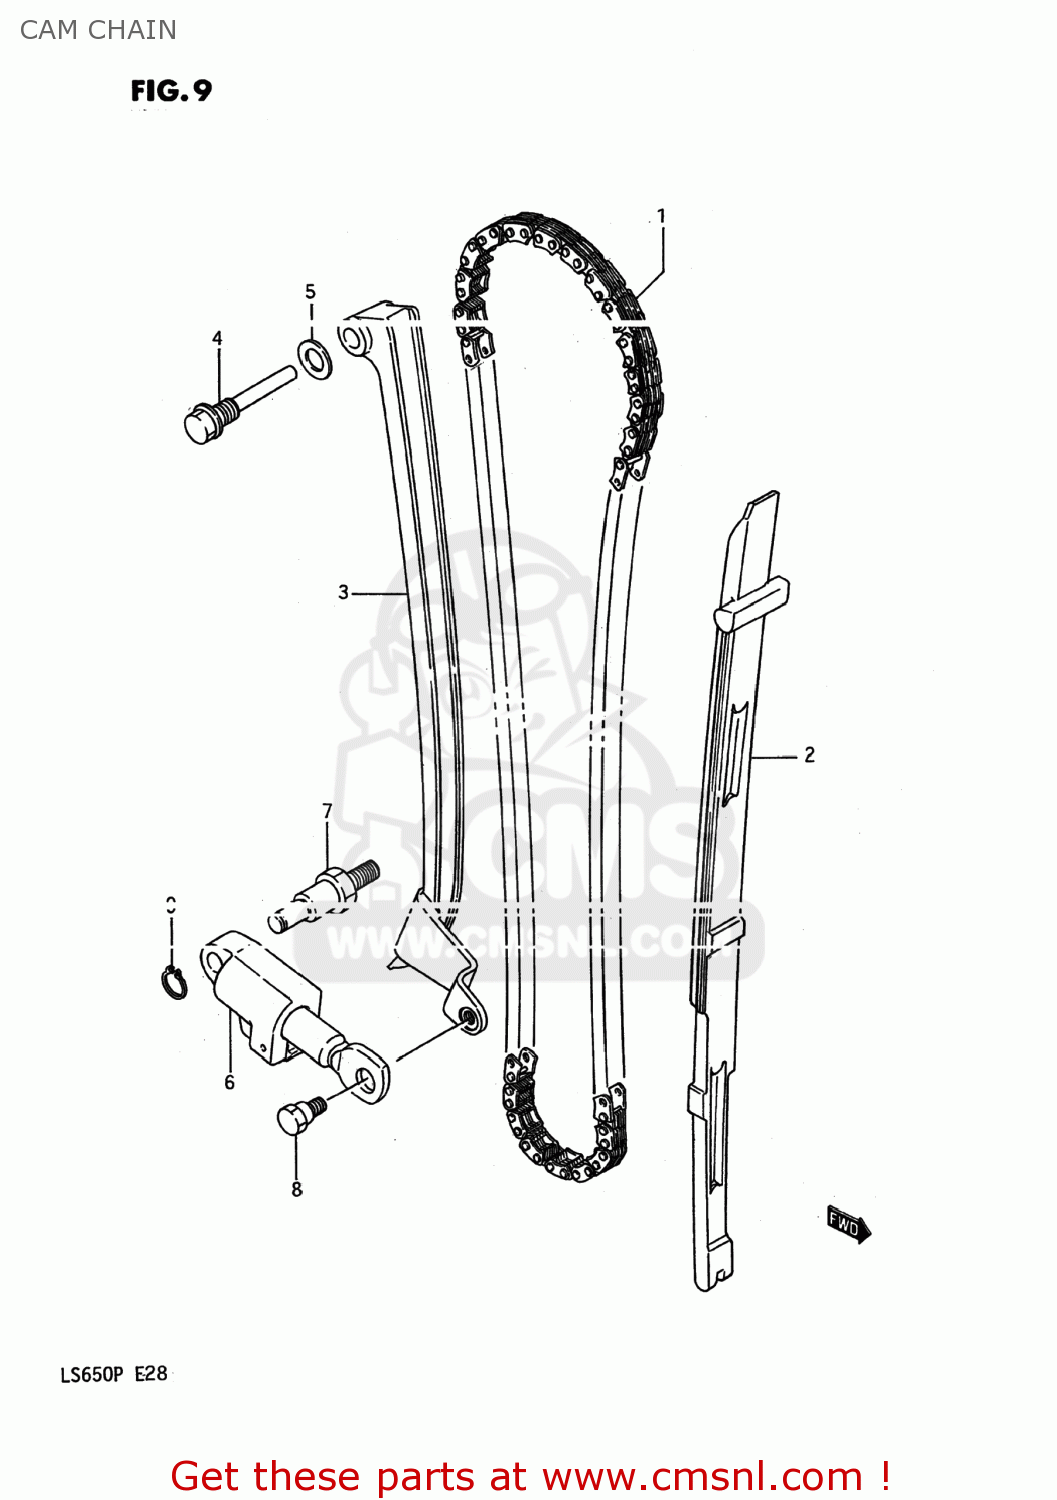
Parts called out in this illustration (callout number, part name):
1	CHAIN,CAMSHAFT DRIVE
2	GUIDE,CAM CHAIN
3	TENSIONER,CAM CHAIN
4	BOLT,CAM CHAIN TENSIONER
5	GASKET 8.2X14X1 (NAS)
6	ADJUSTER ASSEMBLY,TENSIONER
7	BOLT,STUD
8	BOLT
9	CIRCLIP
